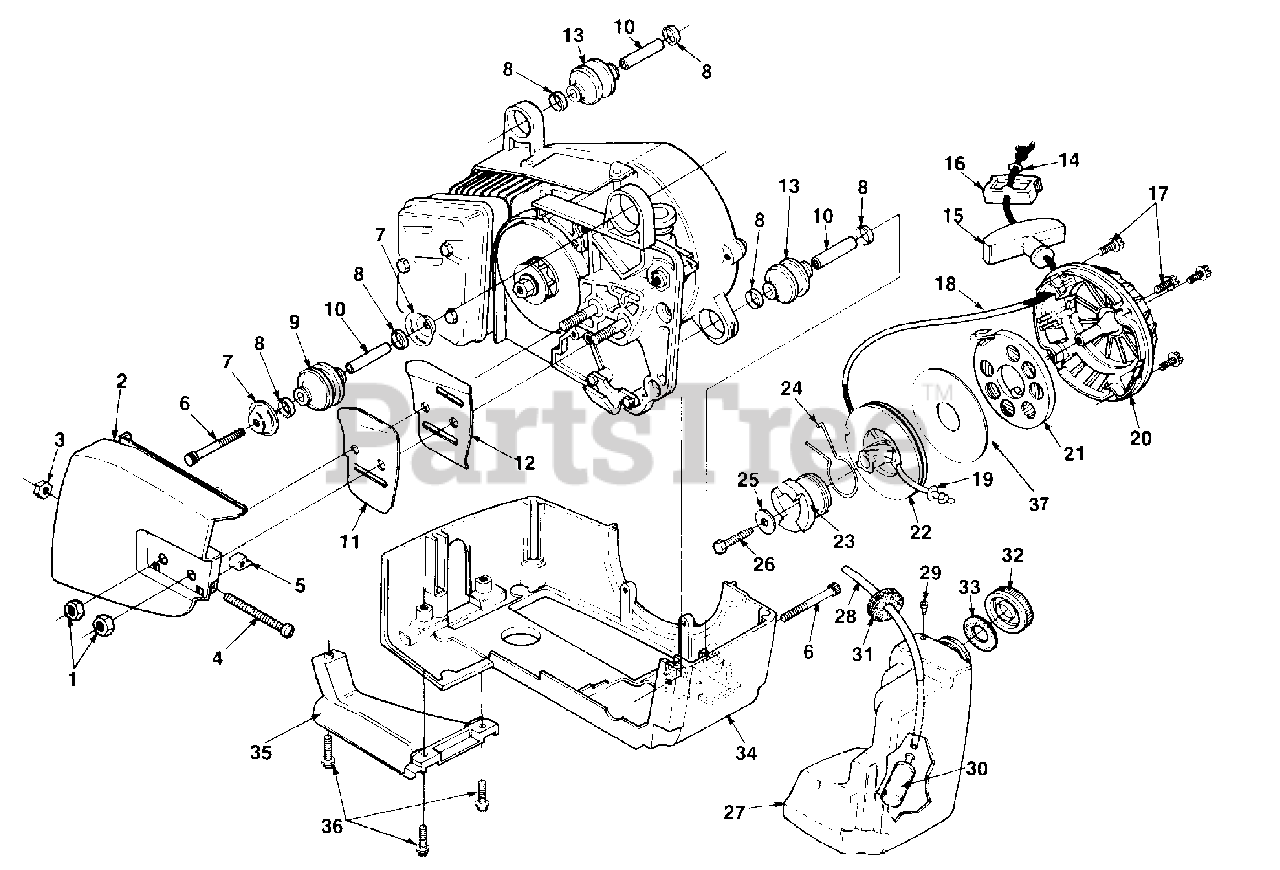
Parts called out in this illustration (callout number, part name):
1	NUT- Hex (5/16-18)
2	COVER- Drivecase
3	NUT- Hex (10-32)
4	SCREW- Guide bar adjusting
5	PIN- Guide bar adjusting
6	SCREW- Cap socket hd. (10-24 x 1 3/4)
7	WASHER- Vibration isolator
8	RING- Vibration isolator
9	ISOLATOR- Vibration
11	PLATE- Guide bar (outer)
12	PLATE- Guide bar (inner)
13	ISOLATOR- Vibration
14	WASHER- Flat (#8)
15	GRIP- Starter
16	INSERT- Rope
17	SCREW- (8-32 x 1/2)
18	ROPE- Starter
19	WASHER- Nylon
20	HOUSING- Starter
21	SPRING- Rewind w/retainer
22	PULLEY- Starter
23	RATCHET- Starter
24	LEVER- Ratchet
25	WASHER
26	SCREW- Thd. forming (#10 x 1 1/4)
27	TANK- Fuel
28	TUBING- 7 1/2 (fuel)
29	VALVE- Check
30	FILTER- Fuel
31	SEAL- Foam
32	CAP- Fuel
33	GASKET- Filler cap
34	HOUSING- Engine (bottom)
35	BRACE- Handle
36	SCREW- Sems hex hd. (10-24 x 3/4)
